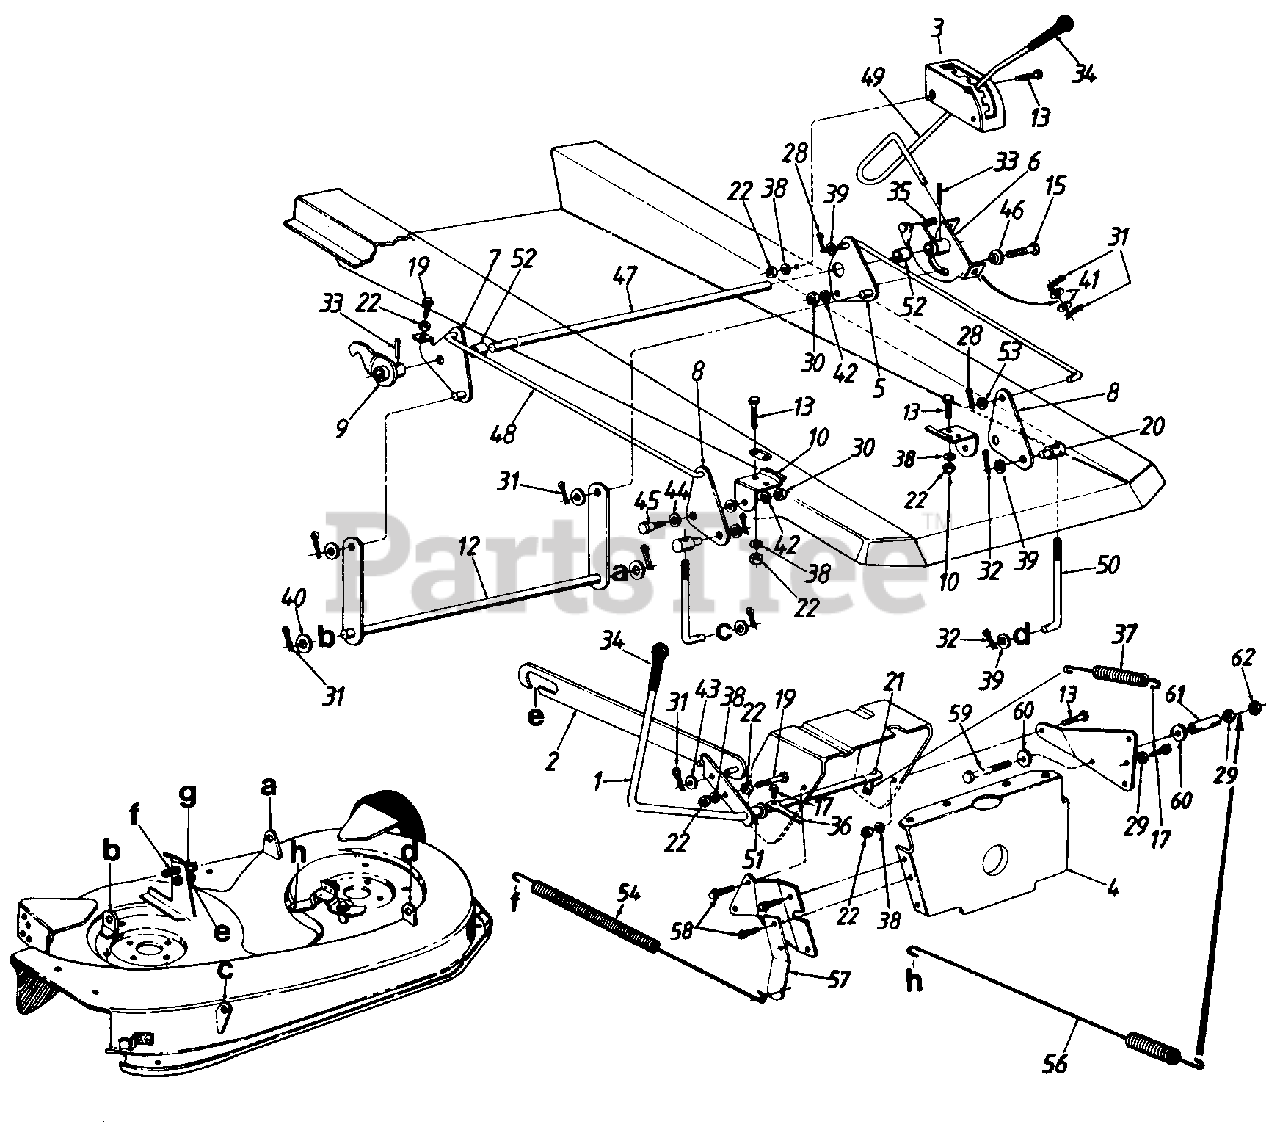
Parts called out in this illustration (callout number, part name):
1	Blade Engagement Lever Ass'y.
5	Deck Lift Brkt. Ass'y.
6	Deck Lift Handle Retainer Ass'y.
7	Deck Lift Brkt. Ass'y.
8	Deck Lift Bracket
9	Deck Lift Float Brkt Ass'y.
10	Deck Lift Pivot Brkt.
12	Stabilizer Shaft Ass'y.
13	Hex Bolt 5/16-18 x .75" Lg.
15	Hex Bolt 3/8-16 x l" Lg.
17	Hex Wash. Hd. Scr. 1/4-20 x 1.5" Lg.
19	Hex Wash.-Tap Scr. 5/16-18 x 1.25" Lg.
21	Clevis Pin
22	Hex Nut 5/16-18 Thd.
28	Cotter Pin 8/32" Dia.
29	Hex Nut 1/4-20 Thd.
30	Hex Nut 3/8-16 Thd.
31	Internal Cot. Pin 1/2" Dia.
32	Int. Cot. Pins 3/8" Dia.
33	Spring Pin Spir. 1/4" Dia.
35	Compression Spring 1.04"
36	Switch Actuator
37	Ext. Spring 5.86" Lg.
38	L-Wash 5/16" l.D.
39	Fl-Wash. .385 I.D. x .62
40	Fl-Wash. .635 I.D. x 1.12
41	Fl-Wash. .531 I.D. x .930
42	L-Wash. 3/8" l.D.
43	Fl-Wash. .385 I.D. x .87 O.D.
44	Spring Washer .530 I.D.
45	Shld. Bolt .500" Dia. x .215"
46	Shld. Spacer .625" l.D.
47	Rear Hgt. Adj. Shaft
50	J-Bolt 5.4" Lg.
51	Spacer.511 I.D.
52	Spacer .885 I.D.
53	Fl-Wash. 5/16" l.D.
54	Ext. Spring 22.05" Lg.
56	Ext. Spring 15.38" Lg.
57	Spring Anchor
58	Hex Wash. Hd. AB-Tap Scr. 1/4 x.62" Lg.
59	Hex Bolt 1/4-20 x 2.5" Lg.
60	Fl-Wash. .25" l.D. x .93" O.D.
61	Spacer.255" l.D.
62	Hex L-Nut 1/4-20 Thd.
